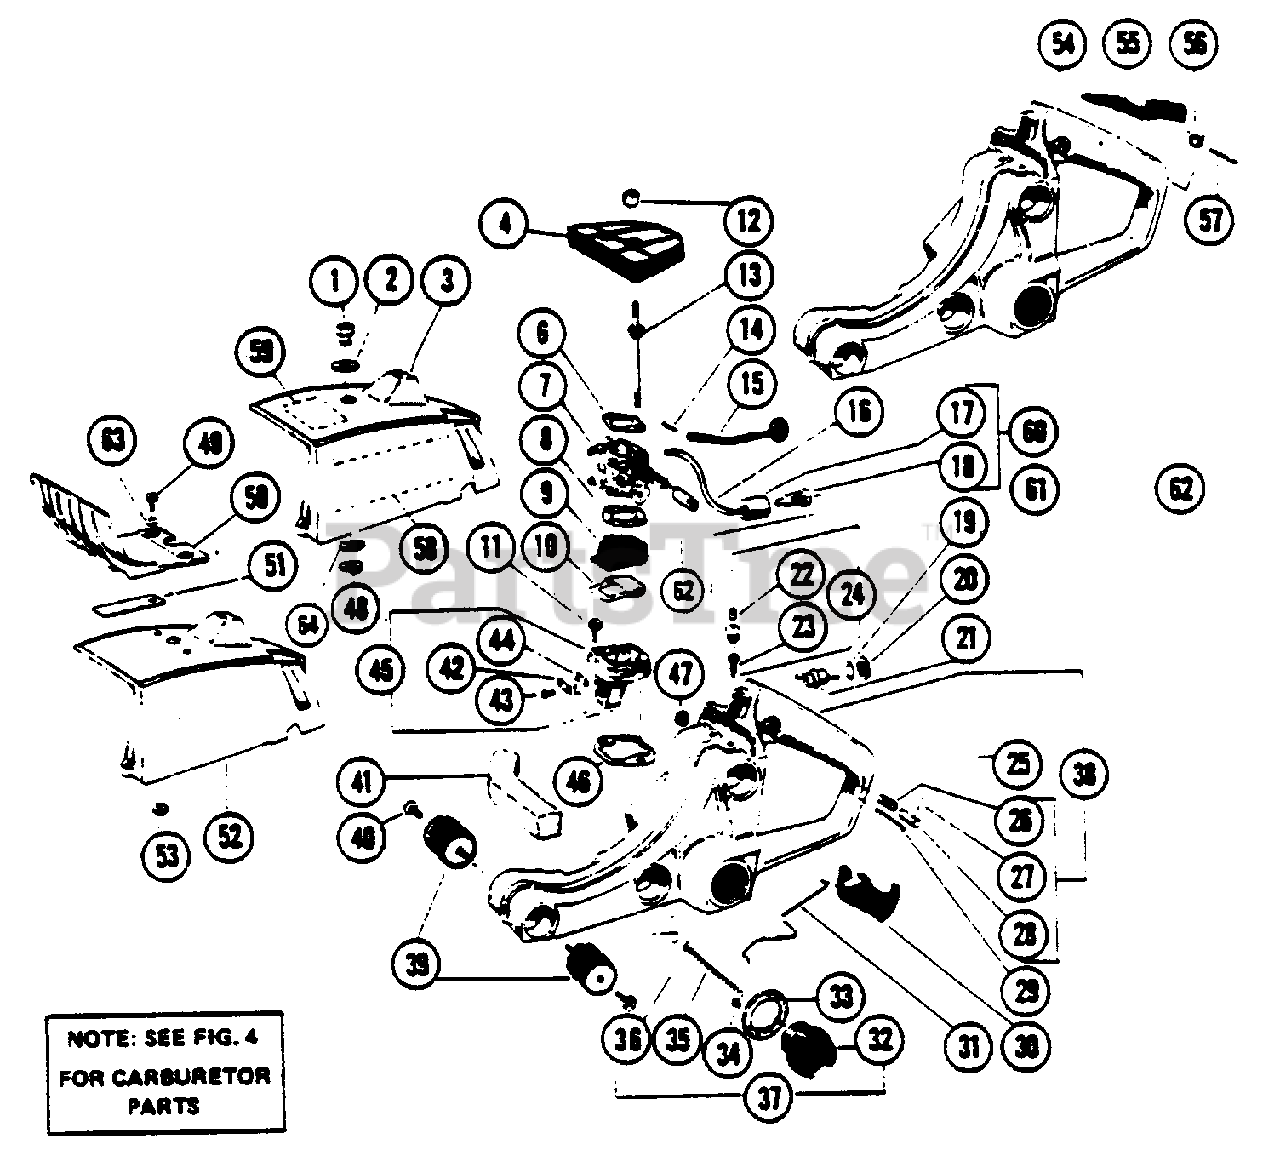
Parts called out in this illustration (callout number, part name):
1	Nut - Cylinder Cover
2	Washer - Cylinder Cover Nut
3	Cover - Cylinder
4	Air Filter - Assy.
4A	Winter Filter
6	Plate - Air Filter
7	Carburetor Ass'y. (Model 4200)
8	Gasket - Carburetor Included in Gasket Kit 69025
9	Adaptor - Carburetor
10	Gasket - Carburetor Adaptor Included in Gasket Kit 69025
11	Screw - 10-24 x 3/4
12	Nut - Air Filter
13	Stud - Carburetor
14	Cotter Pin - Choke Rod
15	Choke Rod
16	Line - Fuel Pick-up (Bulk No. 8136)
17	Filter - Fuel (Felt)
18	Weight - Fuel Pick-up (includes 17)
19	Lockwasher - Switch Mounting
20	Nut - Switch Mounting
21	Switch - Ignition
22	Filter - Fuel Tank Vent
23	Check Valve - Fuel Tank Vent
24	Vent Ass'y. - Fuel Tank (includes 22 & 23)
25	Decal - Starting Instructions
26	Spring - Throttle Lock Button
27	Pin - Lock Button
28	Button - Throttle Lock
29	Pin - Trigger Shaft
30	Trigger - Throttle
31	Rod - Throttle
32	Fuel Cap
33	Gasket - Fuel Cap Included in Gasket Kit 69025
34	Screw - 8-32 x 3/8 5200 Only
35	Chain - Fuel Cap 5200 Only
36	Retainer - Fuel Cap Chain 5200 Only
37	Fuel Cap Ass'y. 5200 Only (includes 32, 33, 34, 35 & 36)
38	Fuel Tank & Handle Ass'y. (includes 26, 27 & 28)
39	Vibration Isolator
40	Screw - 10-24 x 1/2
41	Seal - Sawdust Included in Gasket Kit 69025
42	Stop - Reed
43	Screw - 4-40 x 1/8 pan head
45	Reed Valve Ass'y. (includes 42, 43 & 44)
46	Gasket - Reed Valve Included in Gasket Kit 69025
47	Grommet - Choke Rod Included in Gasket Kit 69025
48	Retaining Ring - Cylinder Cover
49	Screw - Hand Guard OPTIONAL
50	Hand Guard OPTIONAL
51	Spring - Hand Guard OPTIONAL
52	Cyl. Cover (for Hand Guard) OPTIONAL
53	Nut - Hand Guard OPTIONAL
54	Fuel Tank & Handle Ass'y. OPTIONAL (includes 26, 27, 28, 55, 56 & 57)
55	Lever - Throttle Lock-Out
56	Spring - Throttle Lock-out
57	Pin - Throttle Lock-out
58	Decal - Cvl. Cover, Side (5200 only)
59	Decal - Cvl. Cover, top (5200 only)
60	Fuel Pick-up Ass'y. (5200 only)
61	Fuel Line & Filter Ass'y. (5200 only) Includes Item No. 60
62	Grommet - Carb. Adj. Screws
63	Washer - Hand Guard
64	Washer-Curved spring
